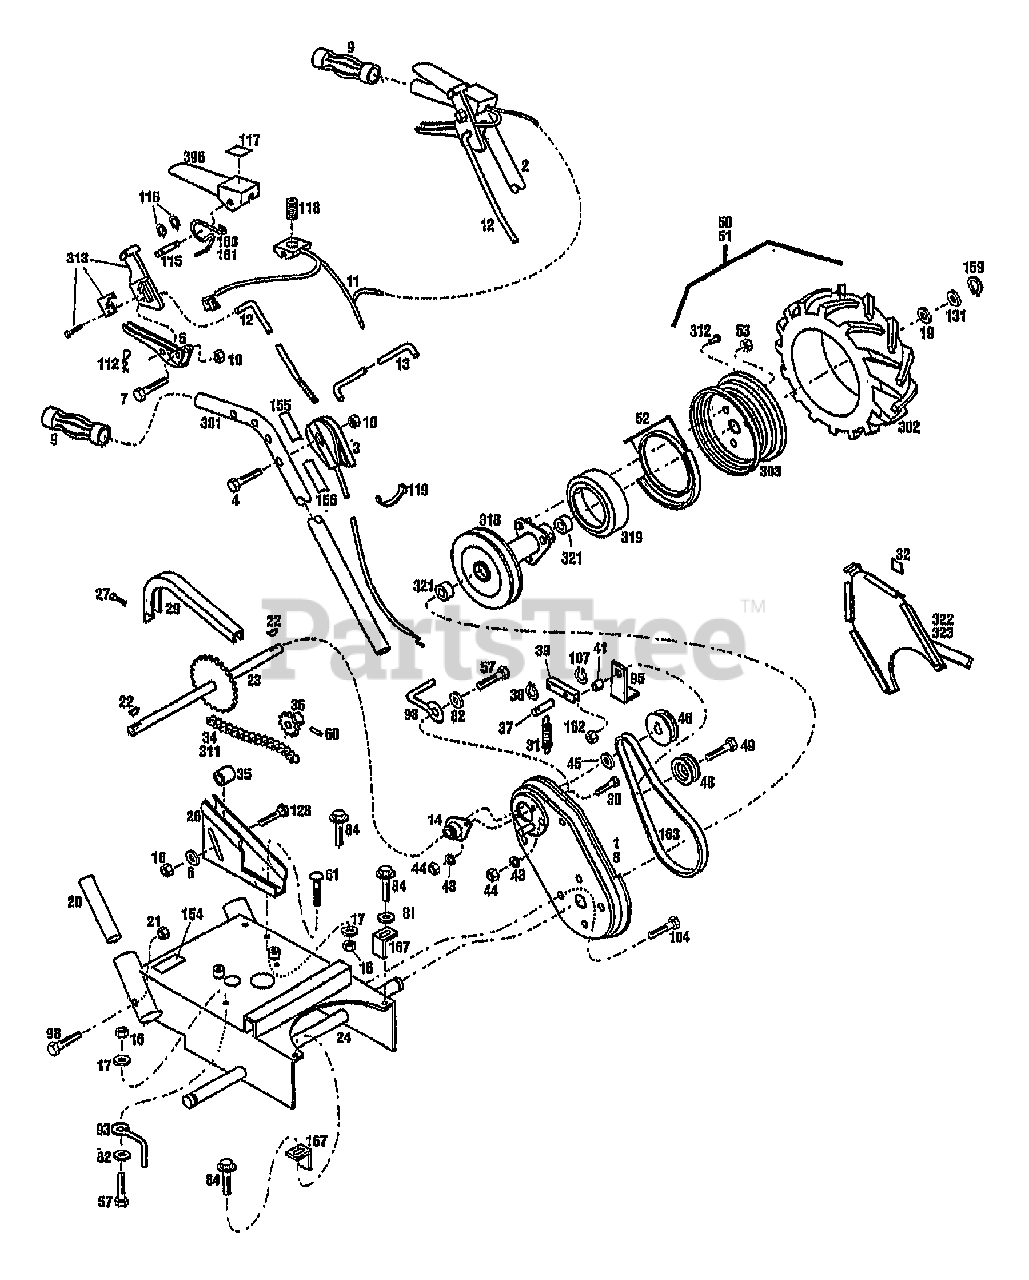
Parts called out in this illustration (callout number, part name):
1	ASSM-BELT GUARD LH
2	HANDLEBAR-LH
3	ASSM-THROTTLE
4	SCR-HH 1/4-20X2.0 G5
5	LEVER-WHEEL CLUTCH
6	WASHER-FLAT 5/16 SAE
7	SCR-HH 1/4-20X1.5 G5
8	ASSM-BELT GUARD RH
9	GRIP-FLEX
10	NUT-H/LK 1/4-20
11	HARNESS-OPERATOR INTERLK (INCL. 313-315)
12	ROD-WHEEL CLUTCH
13	BRIDGE-HANDLEBAR E-COAT
14	BEARING-FLANGE
16	NUT-HEX 5/16-18
17	WASHER-LK .312 INT TOOTH
19	WASHER-1.5X.812X.134
20	ABSORBER-SHOCK
21	NUT-TOP/LK 5/16-18
22	KEY-WOODRUFF .188X.75
23	ASSM-COUNTER SHAFT-PLATED
24	DECK-ENGINE
26	BRKT-CHAIN IDLER PNT
27	SCR-HW M10-24X.5 STH
29	COVER-CHAIN PNT
30	SCR-CARR 1/4-20X.50
31	CLUTCH-SPRING WHEEL
32	DECAL-INST TOP
34	CHAIN W/LINK (INCL. 311)
35	ROLLER-CHAIN IDLER
36	SPROCKET-CHAIN 12T
37	PIVOT-IDLER ARM
38	RING-RET."E" .300 ID
39	ARM-IDLER WHEEL CLUTCH
41	SPACER-WHEEL IDLER
43	WASHER-LK .25
44	NUT-HEX 1/4-20
45	SPACER-.625 ID
46	SHEAVE-COUNTER SHAFT
48	IDLER-FLAT
49	SCR-HH 3/8-16X2.25 G5
50	ASSM-WHL&SEAL LH GRAY (INCL. 302, 303 & 312)
51	ASSM-WHL&SEAL RH GRAY (INCL. 302, 303 & 312)
52	COVER-BELT SEAL
53	NUT-H/LK 3/8-24
57	SCR-HHC 5/16-18X.75 GR 5
60	PIN-ROLL .188X1.0
61	SCR-CARR 5/16-18X.75
81	WASHER .905X.390X.084
82	WASHER-FLAT 5/16 SAE
84	SCR-HFLK 5/16-18X.75
84	SCR-HH 3/8-16X.75
93	GUIDE-BELT
95	GUIDE-BELT WHL CLUTCH
98	SCR-HH 5/16-18X2.25 G5
104	SCR-HFLK 5/16-18X.625 STH
107	RING-RET."E" .437 ID
112	PIN-CLIP .08
115	PIN-PIVOT .25"
116	RING-CRESCENT EXT
117	DECAL-OPC CONTROLS
118	SPRING-COMPRESSION
119	TIE-CABLE NYLON BLACK
128	SCR-CARR 5/16-18X1.25 G2
131	WASHER-1.25X.765X.049
154	DECAL-OIL DRAIN LOCATION
155	DECAL-THROTTLE {34061/062}
155	DECAL-THROTTLE SETTINGS {34063/064}
156	DECAL-PLACE HAN/PULL ROPE
159	RING-RET."E".577 ID
160	SPRING-CONTROL LH
161	SPRING-CONTROL RH
162	NUT-H/LK 3/8-16
167	GUIDE-BELT
301	HANDLEBAR-RH W/DECAL (INCL. 155 & 156)
302	TIRE-LUG 13X5.00-6
303	ASSM-WHEEL RIM
306	LEVER W/DECAL (INCL. 117)
311	LINK-CHAIN CONNECTOR
312	STEM-VALVE
313	KIT-WHEEL CONTROL LK (S/BAR)
316	PAINT-RED SPRAY CAN POWDER (13OZ. CAN)
317	PAINT-BLACK SPRAY (13 OZ. CAN)
318	ASSM & BEARINGS-WHL HUB
319	SPACER
321	BEARING-BALL
322	ASSM-WHL BELT CVR RH (INCL. 32)
323	ASSM-WHL BELT CVR LH (INCL. 32)
324	KIT-SVC T/B SICKLEBAR (INCL. 163, AIR FILTER ELEMENTS, SPARK PLUG, INSTRUCTIONS)
325	CABLE TIE
